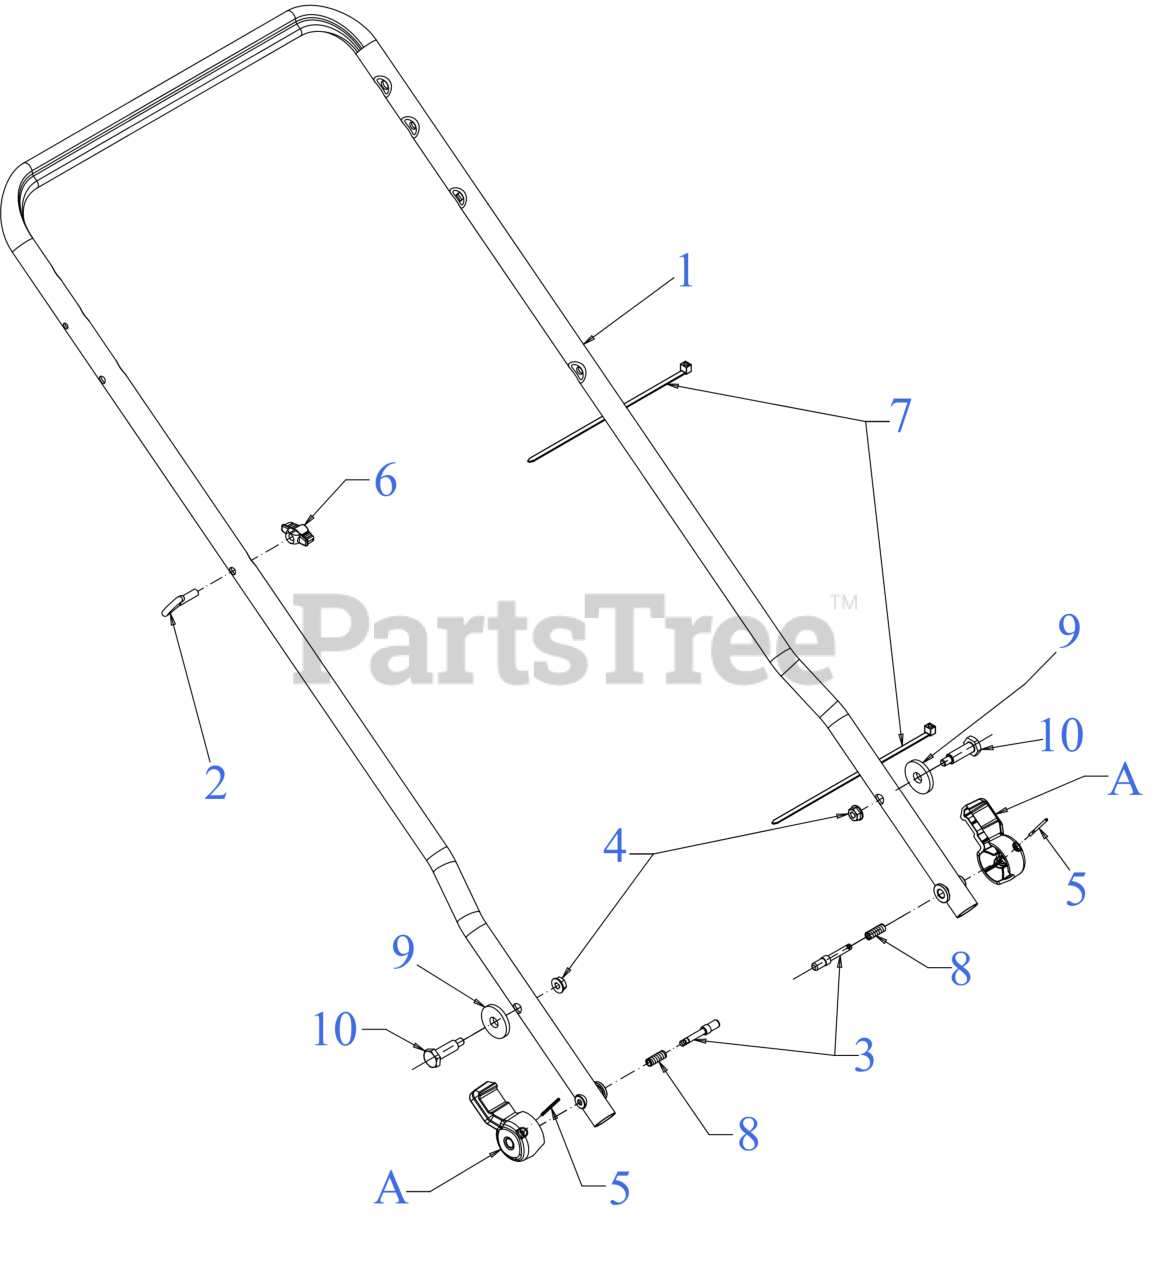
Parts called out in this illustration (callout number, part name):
1	23" HANDLE ASSEMBLY
2	EYEBOLT 1/4-20
3	HANDLE ADJUSTMENT PIN
4	LOCK NUT 1/4
5	SPLIT ROLL PIN 5/64 x 1.38
6	HANDLE KNOB
7	7" CABLE TIE
8	COMPRESSION SPRING
9	FLAT WASHER
10	SHOULDER SCREW
A	LEVER HANDLE KNOB (7/8 RED)
A	LEVER HANDLE KNOB (7/8 YELLOW)
A	LEVER HANDLE KNOB (7/8 BLACK)
A	LEVER KNOB (SBD GRAY)
